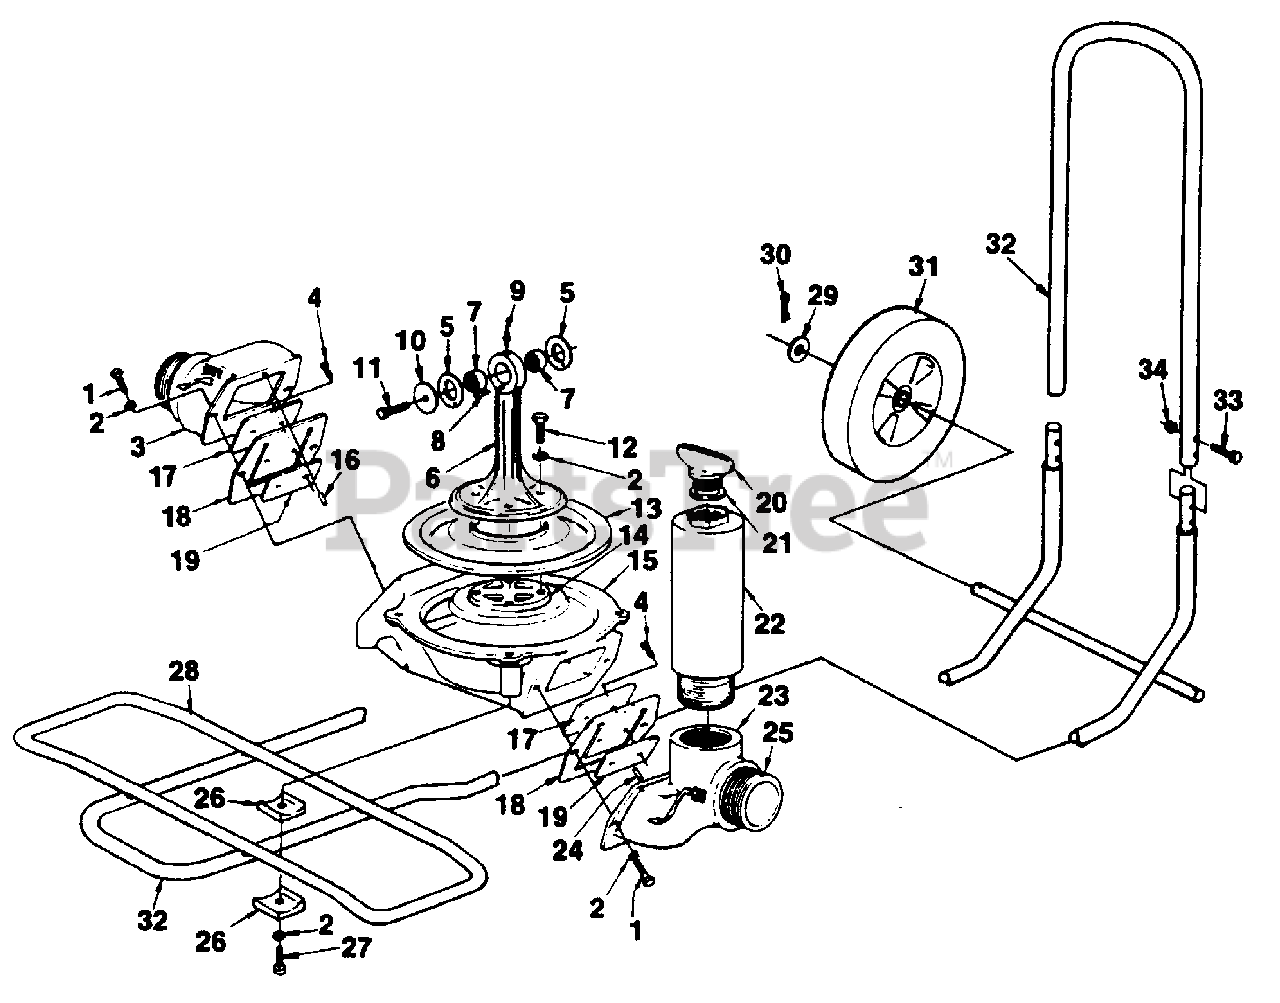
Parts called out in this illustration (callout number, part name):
1	SCREW- Hex hd. (1/2-13 x 1 3/4")
2	WASHER- Lock (1/2")
3	FITTING- Discharge
4	SCREW- Fil. Hd. (10-32 x 1/2")
5	WASHER- Thrust
6	PUMP ROD ASSEMBLY
7	BEARING- Needle
8	PIN- Coiled spring
9	FITTING- Grease
10	WASHER- Pump rod
11	SCREW-Hex hd.(3/8-16 x 3/4")
12	SCREW- Hex hd. (1/2-13 x 1 1/4")
13	DIAPHRAGM
14	PLATE- Diaphragm
15	PUMP BODY ASSEMBLY
16	PIN- Roll
17	VALVE- Plate
18	VALVE- Flapper
19	WEIGHT- Valve
20	PLUG- Wing
21	GASKET- Plug
22	STANDPIPE- 3"
23	SUCTION FITTING
24	PIN- Roll
25	NIPPLE- 3"
26	SADDLE- w/.530 Hole
27	BOLT- (1/2-13 x 2 1/4")
28	PUMP SUPPORT- 3"
29	WASHER- Flat
30	PIN- Cotter
32	HANDLE- Pump
33	SCREW- (1/4-20 x 1 1/2")
